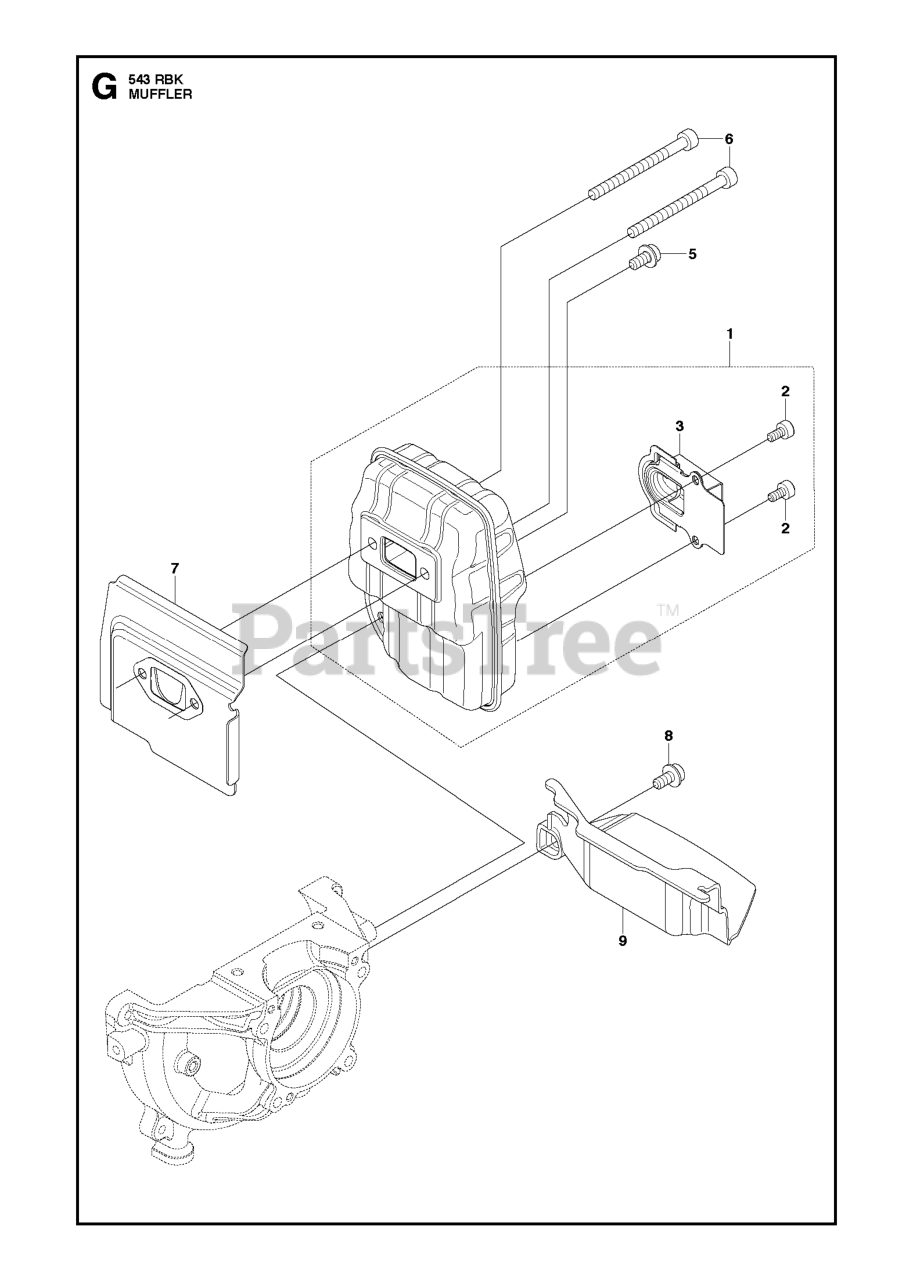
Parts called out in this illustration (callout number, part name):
1	MUFFLER ASSY
5	BOLT (RPLS T495051010-11)
6	BOLT M5X20 T27
8	BOLT (RPLS T495051010-11)
